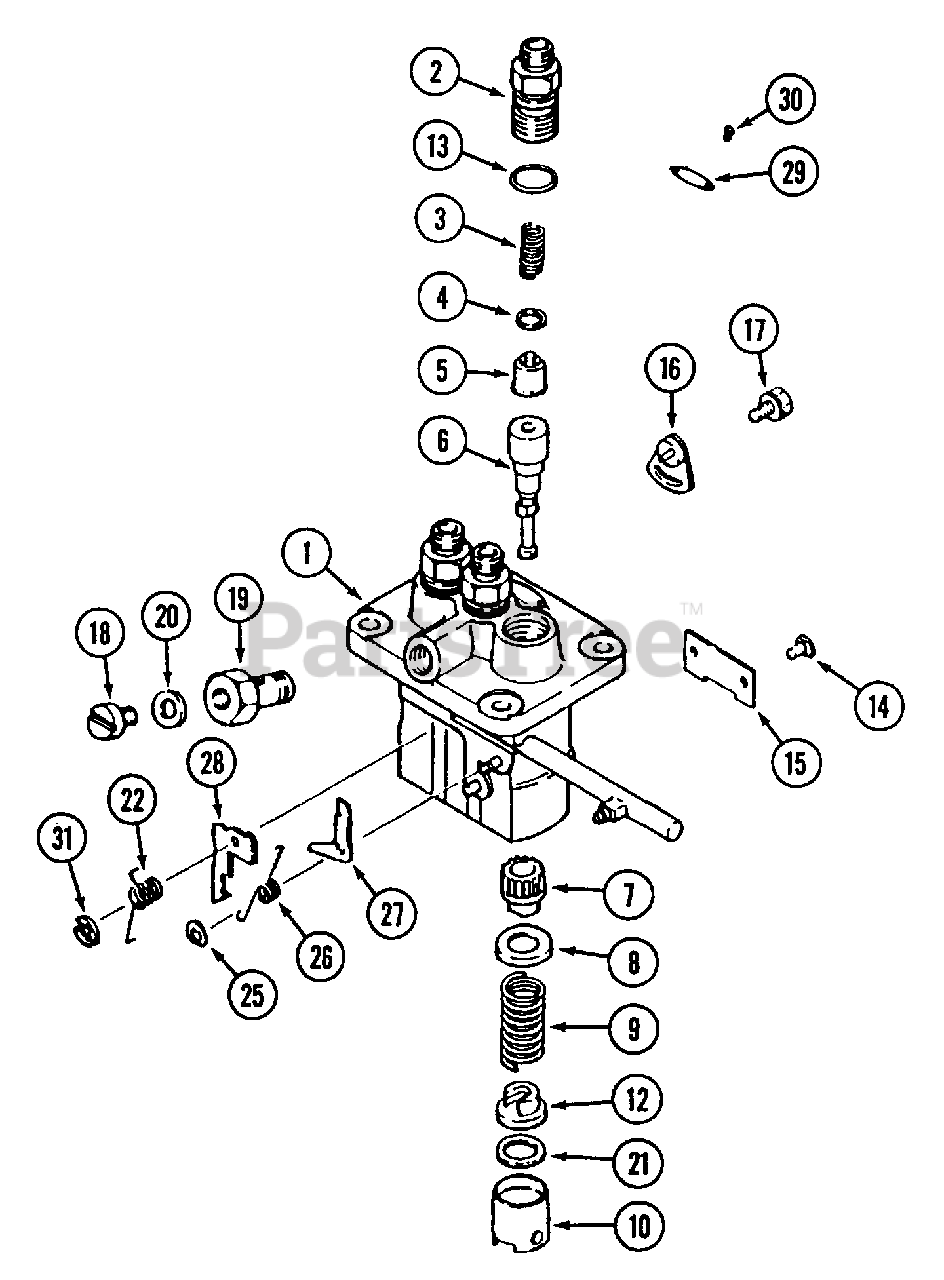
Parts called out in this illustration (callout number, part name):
1	Housing Sub Ass'y., Pump
2	Holder, Delivery Valve
3	Spring, Delivery Valve
4	Gasket, Delivery Valve
5	Delivery Valve Sub Ass'y.
6	Element Ass'y., Pump
7	Sleeve, Plunger Control
8	Seat, Spring Upper
9	Spring, Pump Plunger
10	Tappet Sub Ass'y.
12	Seat, Spring Lower
13	O-Ring
14	Pin, Tappet Guide
15	Plate
16	Plate Ass'y., Adjusting
17	Bolt, w/Washer
18	Screw, Air Breather
19	Screw, Hollow
21	Shim, Plate t=0.6
22	Spring, Smoke Set
26	Spring, Angleich Set
27	Plate, Angleich Set (?)=16.9
28	Plate, Smoke Set (?)=3.5
29	Plate, Name
